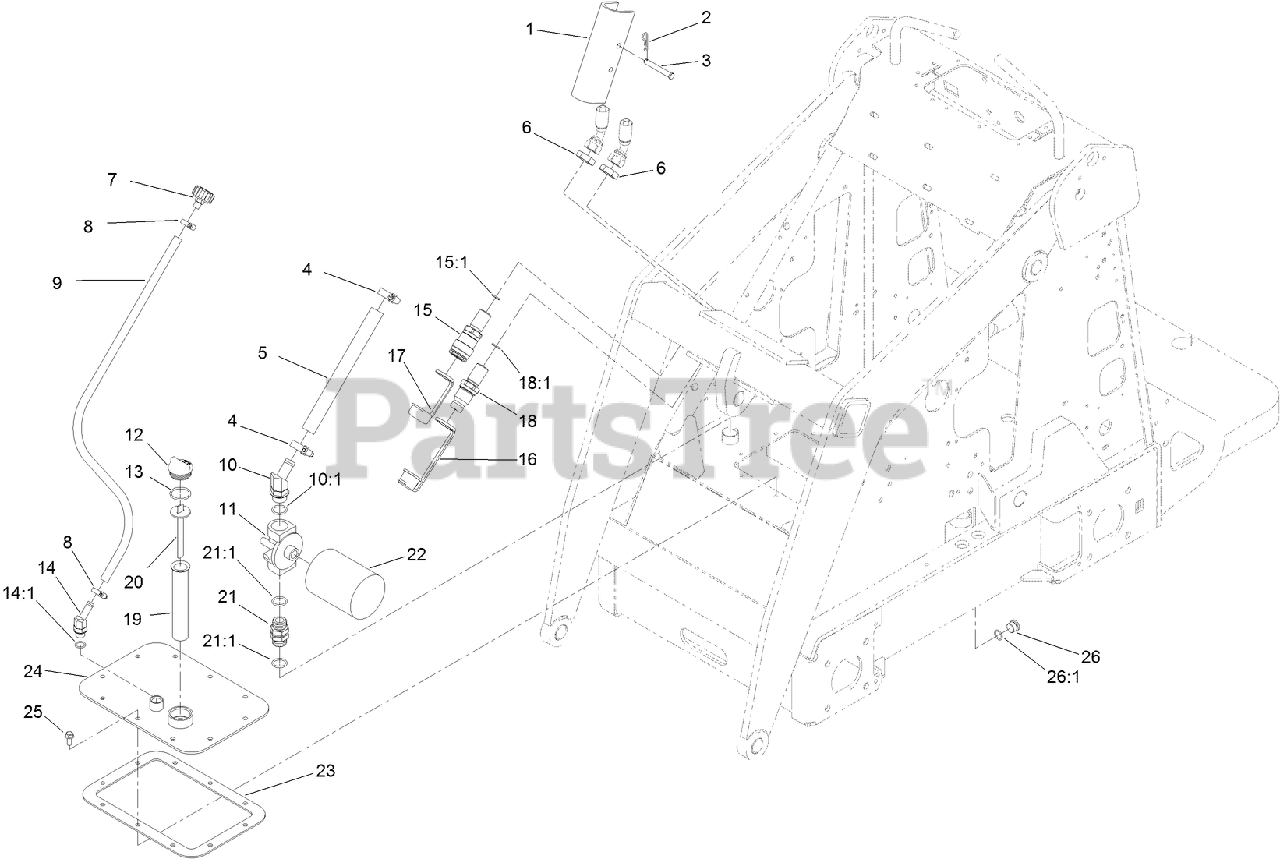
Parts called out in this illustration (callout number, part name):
1	LOCK-CYLINDER
2	PIN-HAIR
3	PIN-CLEVIS
4	CLAMP-HOSE
5	HOSE-HYD, SUCTION, HI
6	NUT-LOCK, BULKHEAD
7	BREATHER
8	CLAMP-HOSE
9	HOSE-VENT
10	ELBOW-45 DEG
10:1	O-RING
11	HEAD-FILTER
12	PLUG-PLASTIC
13	O-RING
14	FITTING-HYD, 45 DEG
14:1	O-RING
15	BULKHEAD COUPLER ASM
15:1	O-RING
16	CAP-DUST, NIPPLE
17	CAP-DUST, COUPLER
18	BULKHEAD NIPPLE ASM
18:1	O-RING
19	FILTER-SCREEN
20	DIPSTICK-OIL
21	FITTING-THREAD, STRAIGHT
21:1	O-RING
22	FILTER-OIL, TRANSMISSION
23	GASKET-COVER
25	SCREW
26	PLUG-HEX
26:1	O-RING
